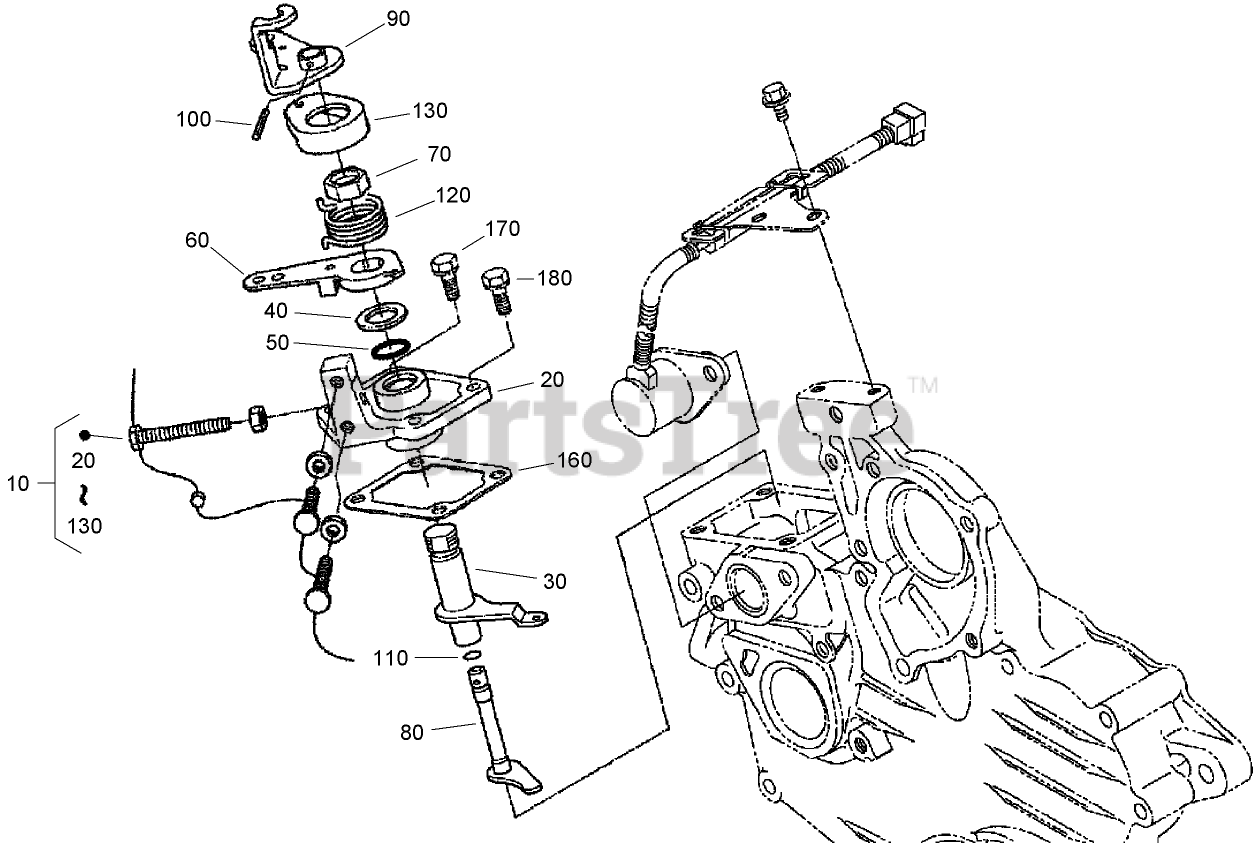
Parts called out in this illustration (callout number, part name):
10	SPEED CONTROL PLATE ASM
20	PLATE-CONTROL, SPEED
30	LEVER-GOVERNOR
40	COLLAR
50	O-RING
60	LEVER-CONTROL, SPEED
70	NUT-CONTROL, SPEED
80	SHAFT-LEVER
90	LEVER-STOP, ENGINE
100	PIN-SPRING
110	O-RING
120	SPRING-RETURN
160	GASKET-PLATE, CONTROL
